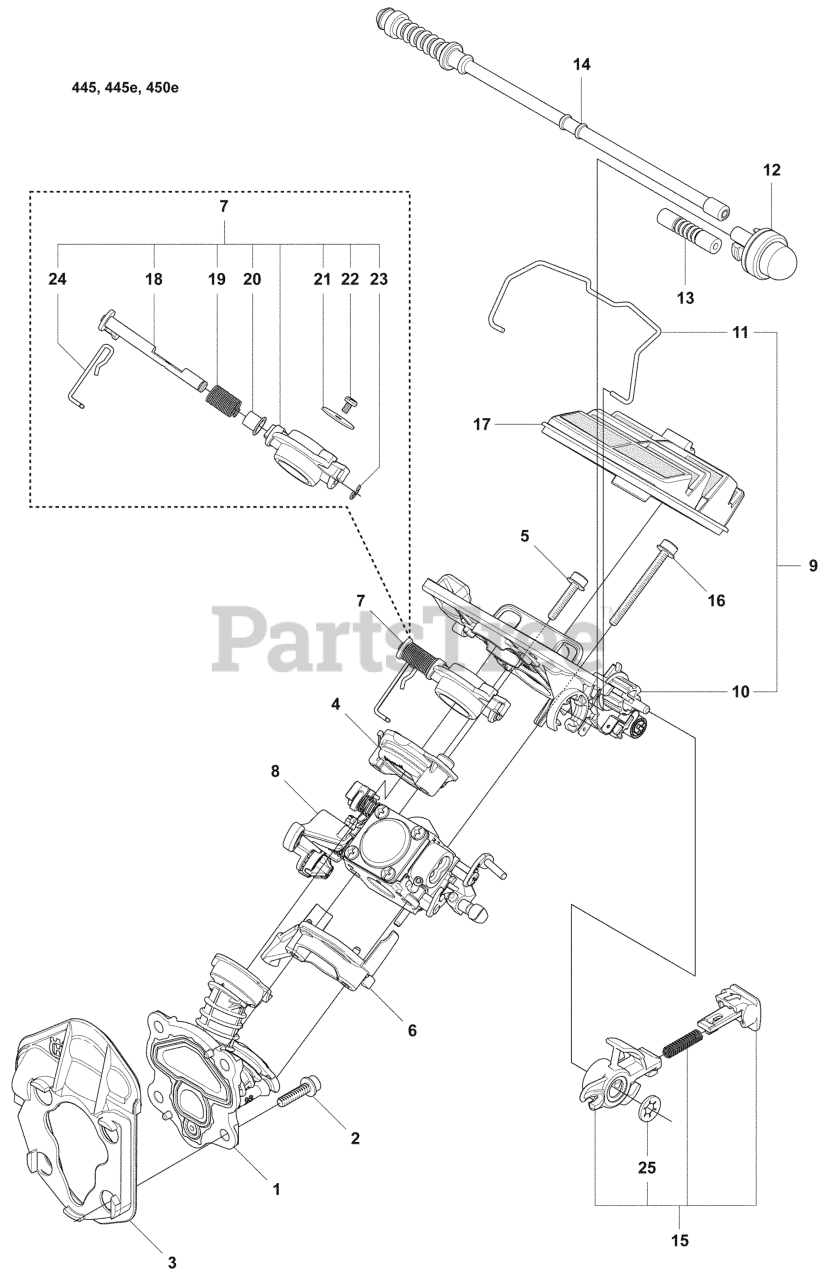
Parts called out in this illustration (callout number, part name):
1	INLET PIPE ASSY
3	INTERMEDIATE WALL
8	CARBURETOR
9	%FILTER HOLDER ASSY
12	AIR PURGE BUBBLE
13	HOSE
14	RP RETURN HOSE
17	AIR FILTER - NYLON (80)
17	AIR FILTER - NYLON (44)
17	AIR FILTER - FELT
18	SHAFT ASSY
25	LOCK WASHER
